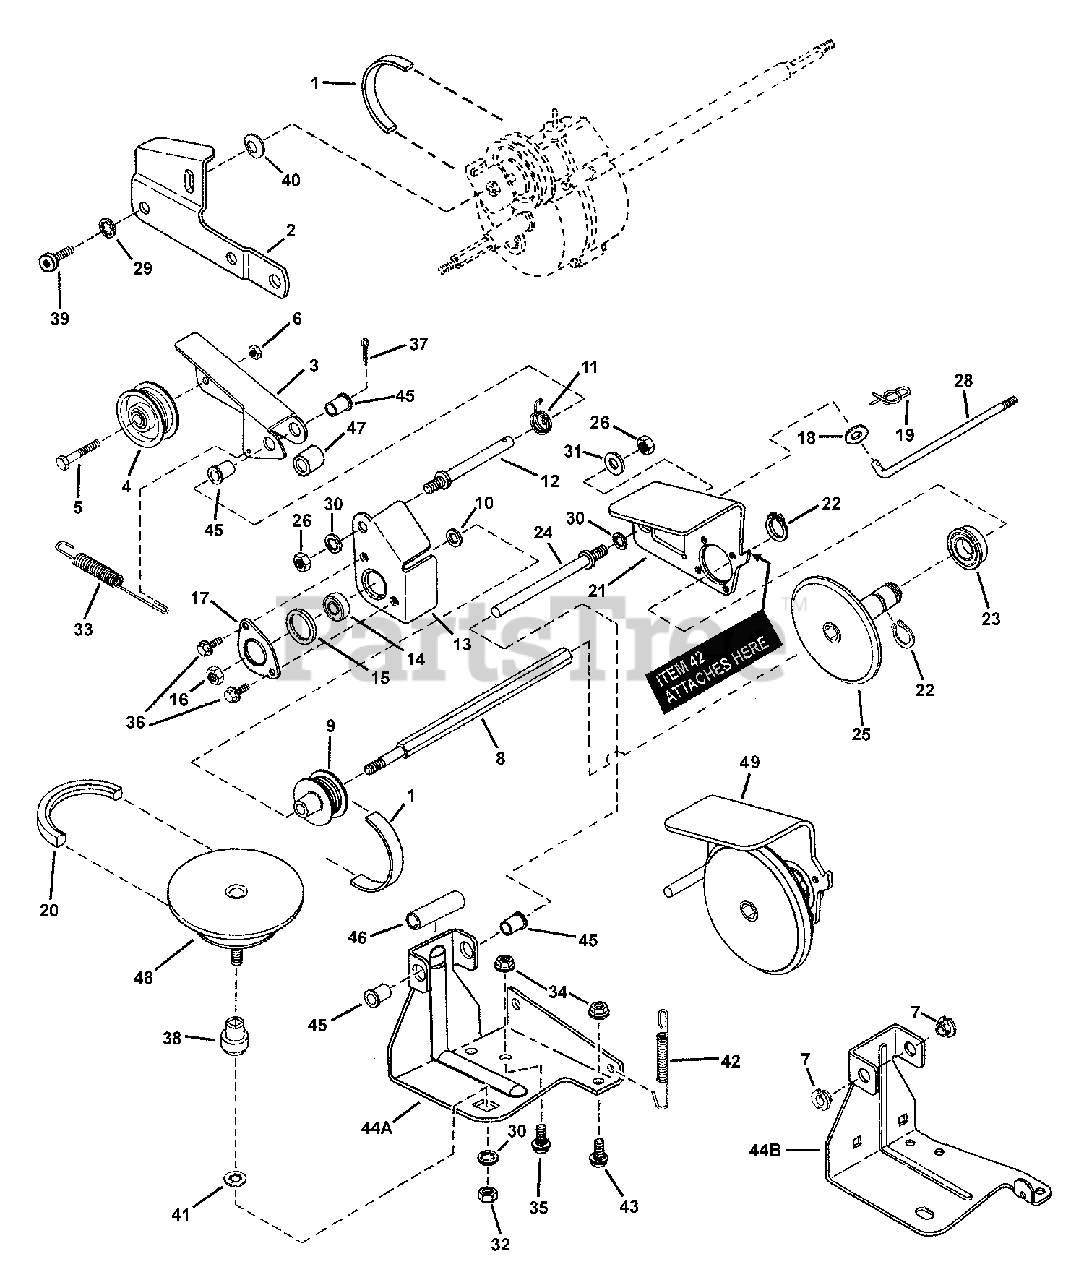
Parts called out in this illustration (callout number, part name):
1	BELT, Poly-V
2	LINK, Differential (Comm.)
3	ARM, Clutch Idler
4	PULLEY, Idler, V21
5	SCREW, 1/4-28 x 1-3/8" Hex Head Cap, GR 5
6	NUT, 1/4-28 Hex Top Lock
7	BUSHING, 3/8" I.D. Nylon
8	SHAFT, Hex Drive
9	PULLEY, Poly-V (2" O.D.)
10	WASHER, 11/32" Flat
11	SPRING, Idler- Torsion
12	STUD, Idler (3/8-24 thread)
13	HOLDER, Bearing (Inner Half)
14	BALL BEARING, Spherical O.D., .38 I.D.
15	O-RING, V21
16	NUT, 3/8-24 Hex Center Lock, GR 5
17	HOLDER, Bearing (Outer Half)
18	WASHER, .28 x .63 x .06 Flat
19	COTTER PIN, .06 x .50 YZ
20	BELT, Engine Drive (Stretch)
21	ASSEMBLY, Thrust Plate & Bearing (includes item #'s 21 & 23)
21	THRUST PLATE, Short
22	RETAINING RING, .625 External
23	BALL BEARING, 3/4" Bore
24	GUIDE, Thrust Plate (3/8-24 thread)
25	DISC, Driven (Cantilever)
26	NUT, 3/8-24 Hex
28	LINK, Transfer (1/4-28 thread)
29	WASHER, 5/16" Internal Tooth Lock
30	WASHER, 3/8" Internal Tooth Lock
31	WASHER, 3/8" Flat
32	NUT, 3/8-16 Hex
33	SPRING, Clutch - 21S
34	NUT, 5/16-18 Hex Flange Lock, GR 5
35	BOLT, 5/16-18 x 1/2", Short Neck Carriage, GR 5
36	SCREW, 1/4-20 x 1/2" Hex Flange Self-Tap
37	COTTER PIN, 3/32 x 1/2"
38	BUSHING, Powdered Metal
39	SCREW, 5/16-18 x 1/2" Pan Head Self-Tap (Torx)
40	WASHER, 44 x .78 x .025 Curved
41	RETAINER, 3/8" Bolt
42	SPRING, Wheel Drive
43	BOLT, 5/16-18 x 5/8" Short Neck Carriage GR 5
44A	BRACKET, Deck
44B	BRACKET, Deck - Replaced (Use # 44A and # 7 or #'s 45 & 46)
45	BUSHING, Flange, .381 x .625 x .62
46	SPACER, .500 x .65 x 1.75
47	SPACER, Idler Arm
48	DRIVE DISC, Steel
48	* KIT, Drive Disc Assembly
49	ASSEMBLY, Driven Disc (includes items 21-26, 30&31)
